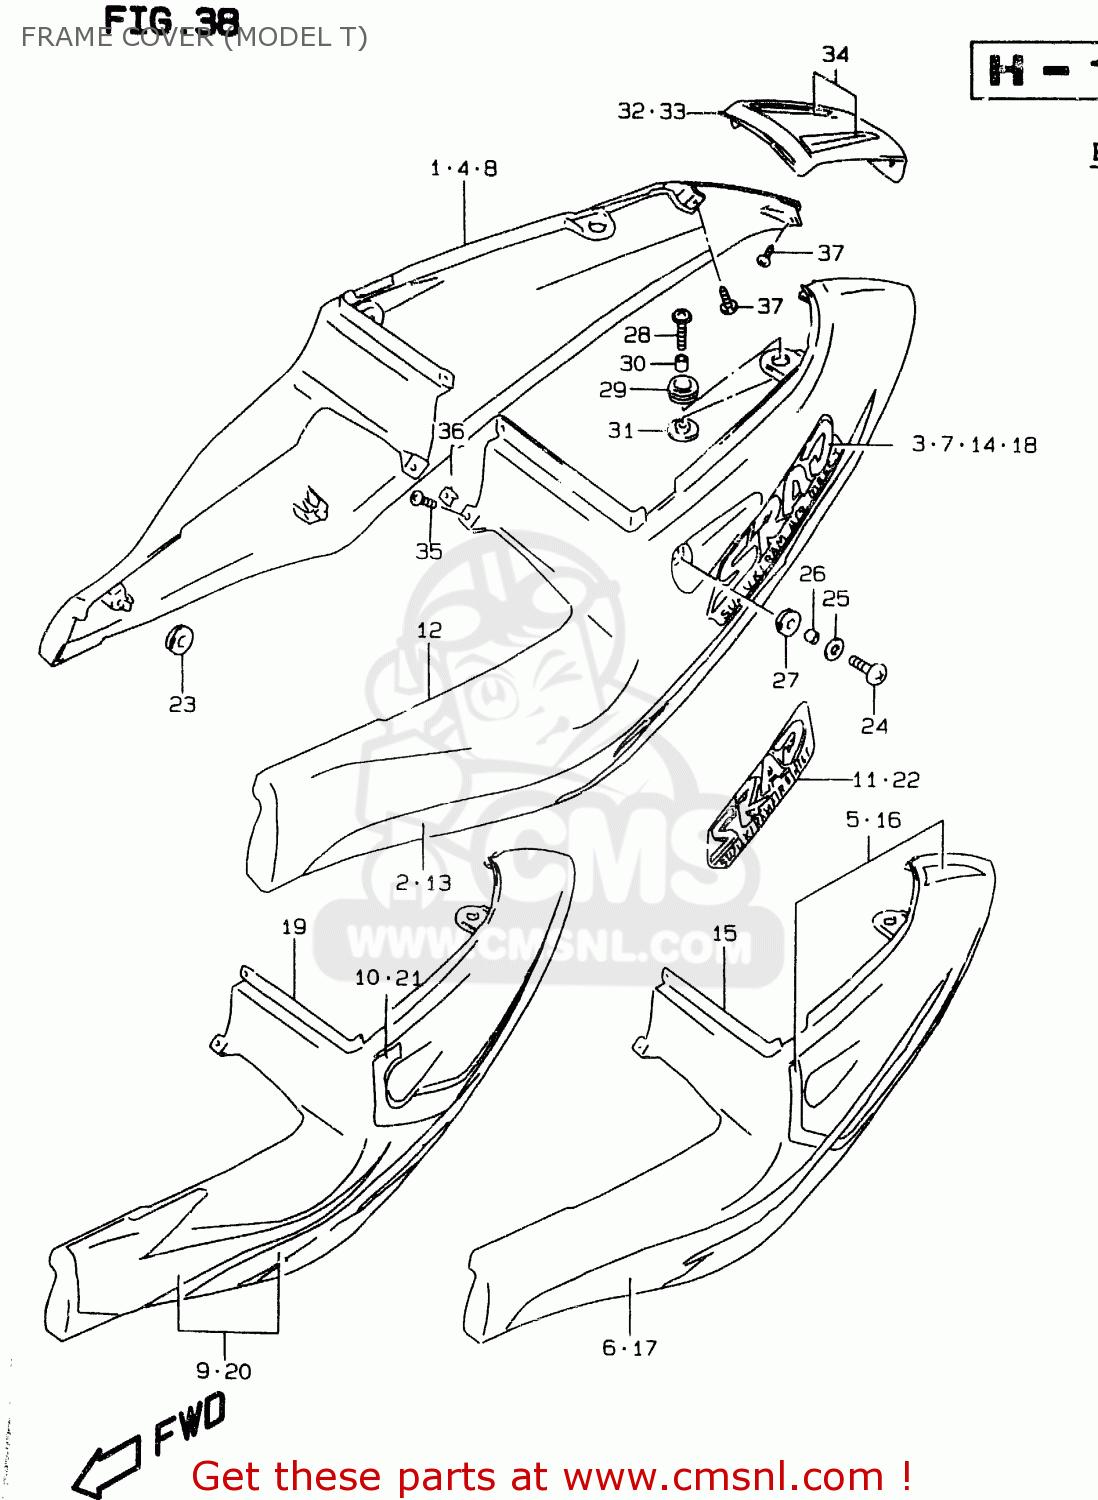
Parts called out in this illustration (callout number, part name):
1	COVER,FRAME,R
2	TAPE,FRAME,R
3	EMBLEM,FRAME C
4	COVER,FRAME,R(BROWN)
5	TAPE SET,FRAME COVER,R(YELLOW)
6	TAPE,FRAME COVER,RIGHT
7	EMBLEM,FRAME COVER
8	COVER,FRAME,R(WHITE)
9	TAPE SET,FRAME COVER,RIGHT
10	TAPE,FRAME COVER,R
11	EMBLEM,FRAME COVER
12	COVER, FRAME LH
13	TAPE, LH (YELLOW)
14	EMBLEM,FRAME C
15	COVER,FRAME,L(BROWN)
16	TAPE SET,FRAME COVER,L(YELLOW)
17	TAPE,FRAME COVER,L
18	EMBLEM,FRAME COVER
19	COVER,FRAME,L(WHITE)
20	TAPE SET,FRAME COVER,LEFT
21	TAPE,FRAME COVER,LEFT
22	EMBLEM,FRAME COVER
23	CUSHION
24	SCREW(6X20)
25	WASHER(6.5X22X1.6)
26	SPACER (6.3X9.1X6.7)
27	CUSHION
28	SCREW(6X25)
29	CUSHION,TAIL COVER UPR
30	SPACER (6,8X10X9.4)
31	CUSHION,FRAME COVER LWR
32	COVER,FRAME CTR
33	COVER,FRAME CTR
34	TAPE SET,FRAME COVER C
35	SCREW
36	NUT
37	SCREW
